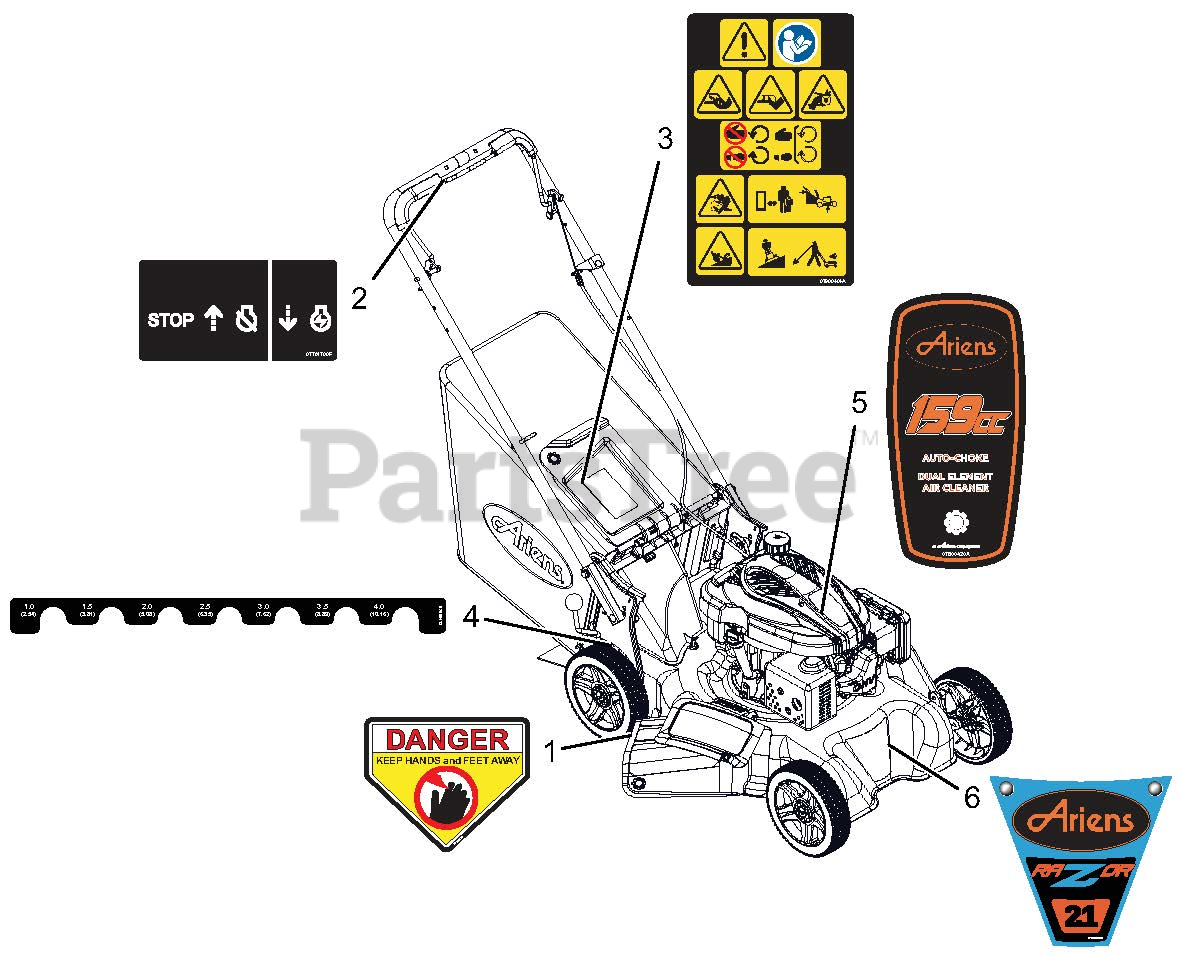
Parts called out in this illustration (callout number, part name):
1	DECAL, DANGER
2	DECAL - ENGINE CONTROL
3	DECAL,MAIN SAFETY_WAW LM
4	DECAL, HOC
5	DECAL, ENGINE STYLE - ARIENS
6	DECAL, ARIENS RAZOR STYLE
